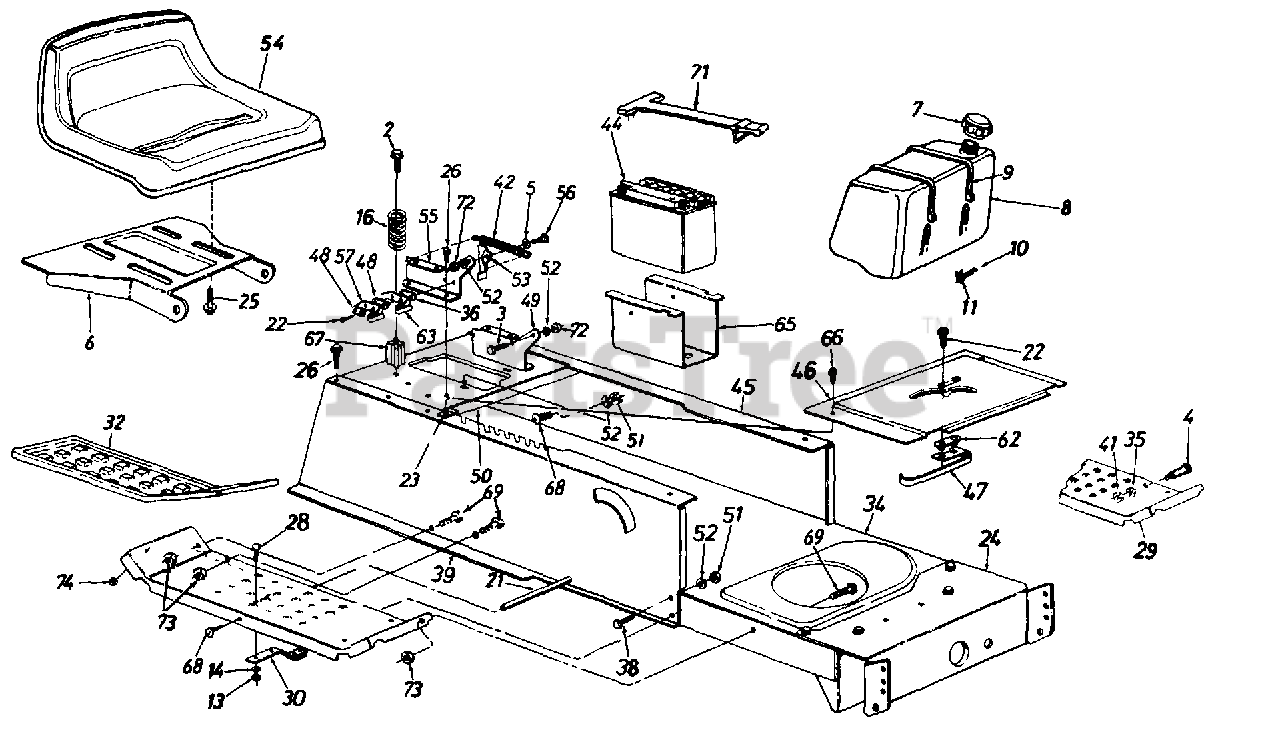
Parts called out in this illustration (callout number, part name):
2	Hex Wash. Kd. Tap Scr. 5/16-18 x 3.25" Lg.
3	Shld. Bolt .437" Dia. x .162"
4	Shld. Bolt .50" Dia. x .84"
5	Spr-Wash. .445" I.D. x .75
7	Fuel Cap
8	Fuel Tank (12.5 H.P. & Smaller)
9	Tie Strap
10	Fuel Line
11	Hose Clamp
13	Hex Nut 1/4-20 Thd.
14	L-Wash. 1/4" I.D.
16	Compression Spring
21	Running Board Rod
22	Hex Wash. Hd. AS-Tap Scr. #8 x .50" Lg.
23	Speed Nut #10Z
25	Hex Tap Scr. 3/8-16 x .62" Lg.
26	Hex Wash. Hd. AB-Tap Scr. 5/16 x .75" Lg.
28	Carriage Bolt 1/4-20 x .62"
32	Rubber Foot Pad - L.H.
35	L-Wash. 3/8" I.D.
36	Insulator Boss Plate
38	Hex Bolt 5/16-18 x .75" Lg."
42	Extension Spring 5.31" Lg
44	12-V Battery
47	Reverse Safety Switch
48	Insulator Plate
52	L-Wash. 5/16" I.D.
53	Seat Lift Brkt
54	Seat 8-7/8" High
56	Shld. Bolt 437" Dia. x 268"
57	Spring Switch (Seat - Outer)
62	Insulator Nut Plate
63	Safety Switch (Seat - Inner)
66	Truss Mach. B-Tap Scr. #10 x 5" Lg.
67	Spring Spacer
68	Truss Mach Scr 5/16-18 x .75"
69	Hex Bolt 5/16-18 x 75" Lg.
71	Battery Retainer Strap
72	Hex Nut 5/16-18 Thd.
73	Hex Sems Nut 5/16-18 Thd.
74	Hex Sems Nut 1/4-20 Thd
